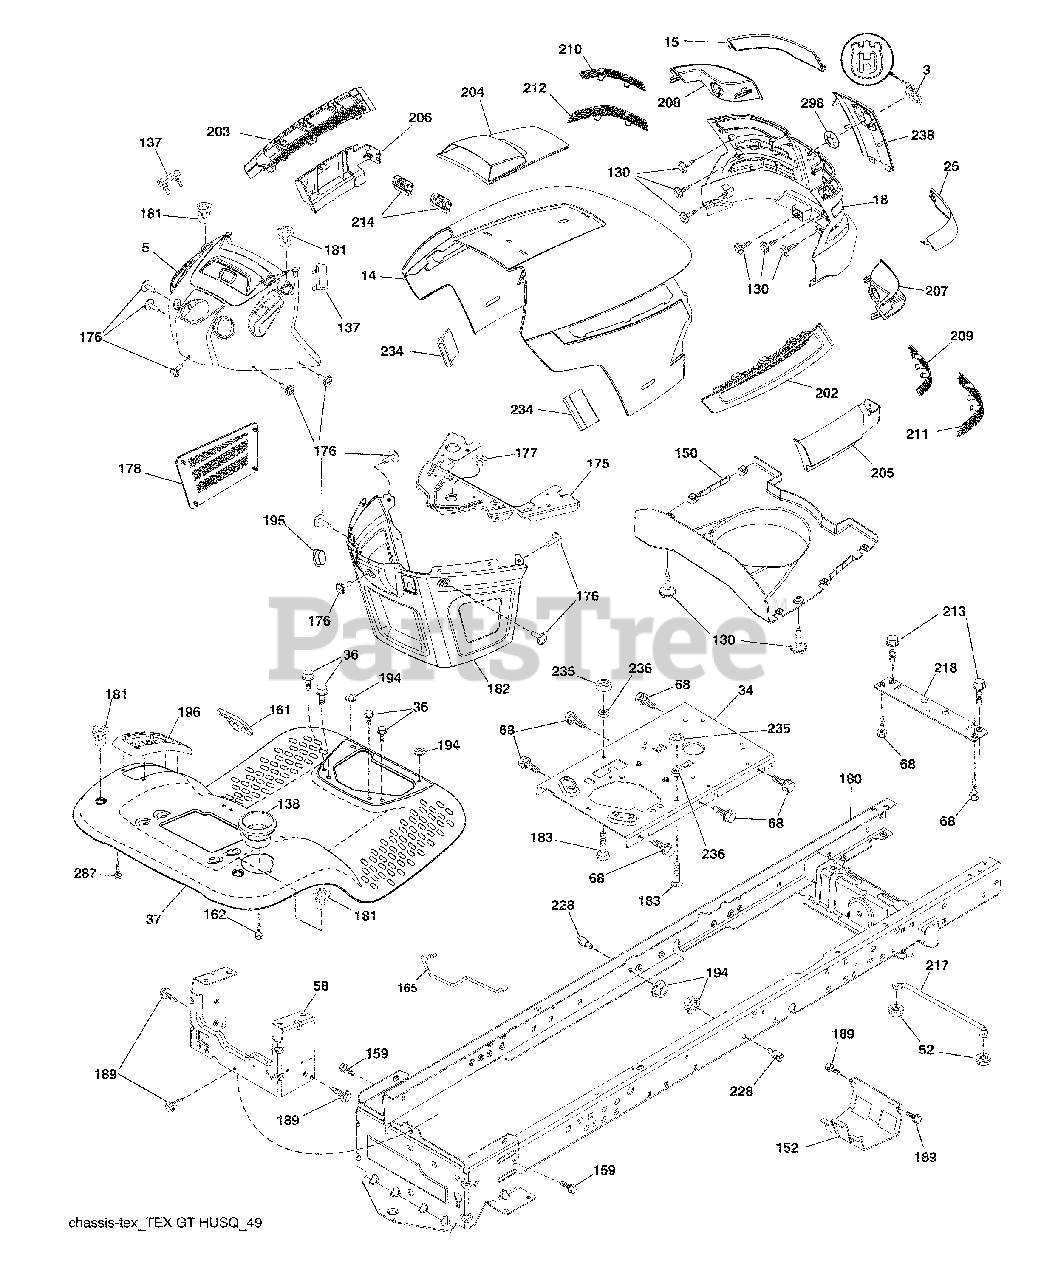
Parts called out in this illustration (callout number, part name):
3	Logo
5	Dash Asm. Husq.
14	Hood
18	Grille Asm.
34	Plate Engine
36	Screw 5/16-18 x 3/4
52	Nut Lock 5/16-18
58	Drawbar Upper
68	Screw Thdrol 5/16-18 x 1/2
130	Screw #10 x 0.750
137	Bumper Dash
138	Cupholder
152	Shield Browning
159	Screw 3/8-16 x 3/4
161	Window Fuel
165	Support Tank Rear
175	Crossmember
176	Screw 10-24 x 5/8
177	Bushing Steering
178	Cargo Net Asm.
181	Bushing Mtg. Fender Crgo
182	Dash Lower
183	Bolt Fin Hex 5/16-18 unc x 1-1/4
189	Screw 5/16-18 x 3/4
194	Nut Lock Hex Flange 5/16-18
195	Plug Hole Dash Lower
196	Console Asm. Deck Lift
202	Vent Side Hood RH
203	Vent Side Hood LH
204	Vent Top Hood
205	Skirt Hood Side RH
206	Skirt Hood Side LH
209	Insert Hex Top RH
210	Insert Hex Top LH
211	Insert Hex Bottom RH
212	Insert Hex Bottom LH
213	Bolt 5/16-18 x 3/4
214	Clip Retainer Tinner
218	X-Piece Hood Stop
228	Stud Fastner
234	Bumper Hood
235	Spacer Fender
236	Nut Lock 5/16-18 unc
287	Screw 1/4-20 x 3/8
